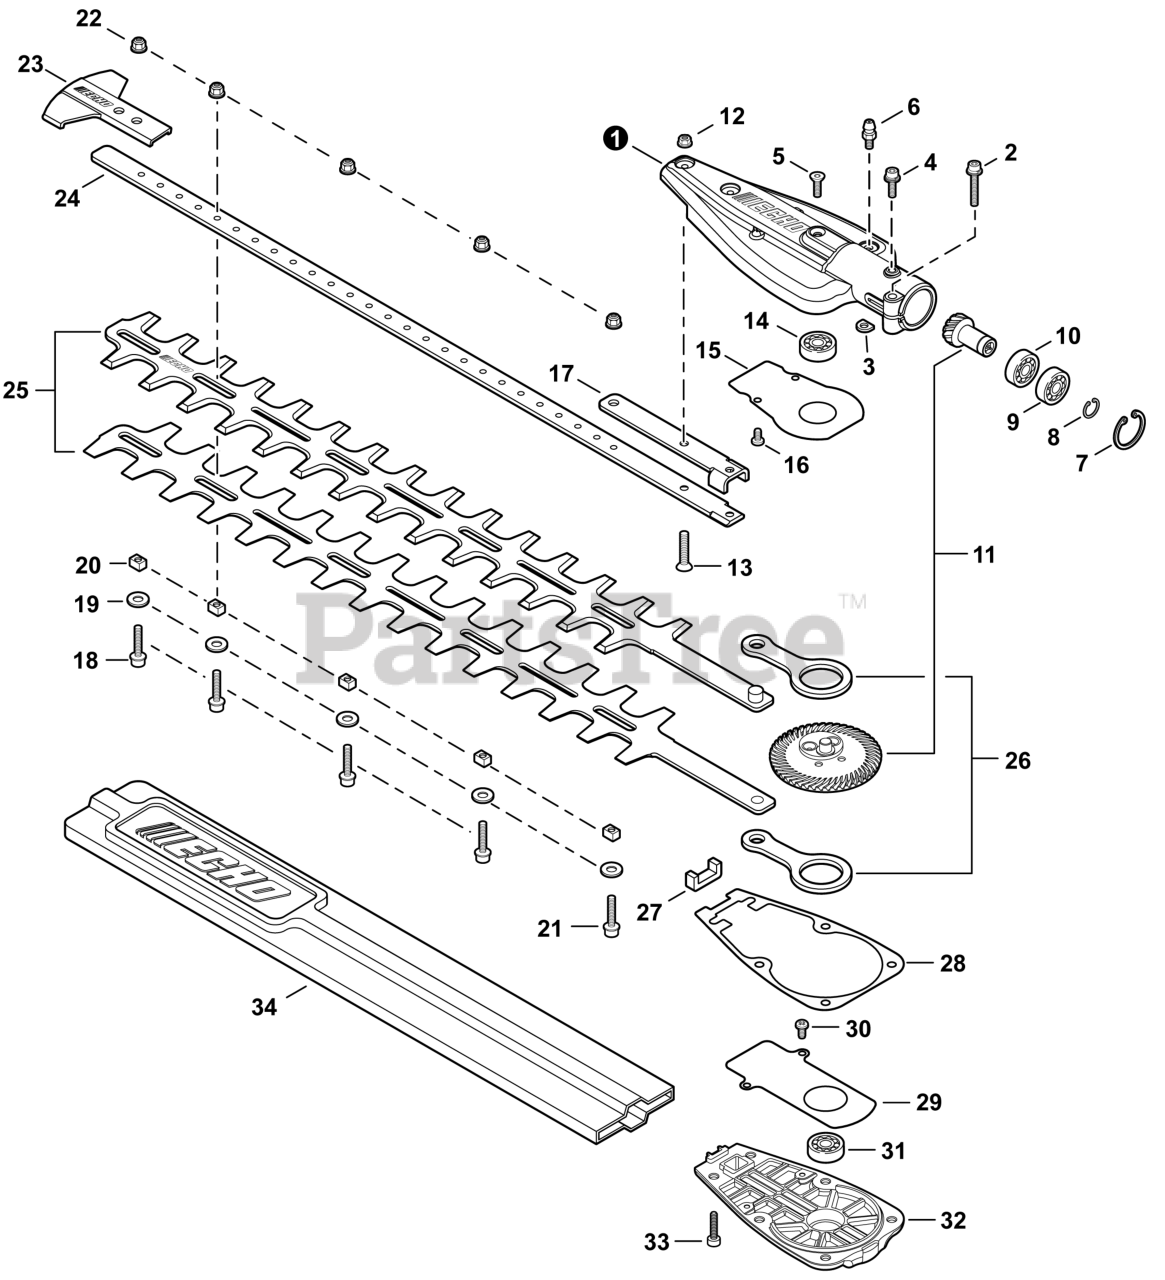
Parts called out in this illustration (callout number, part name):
1	HOUSING, GEAR CASE
2	BOLT 5×25
3	D-WASHER
4	BOLT 5×12
5	SCREW 5×5/8" HD-SOCKET
6	FITTING, GREASE
7	RING, RETAINING Ø24
8	RING, SNAP Ø12
9	BEARING, BALL
10	BEARING, BALL 6901Z
11	GEAR SET
12	NUT, FLANGE M5
13	SCREW 5×18
14	BEARING, BALL 608ZZ
15	PLATE, WEAR
16	SCREW 4×5
17	SUPPORT, BLADE
18	BOLT 5×20
19	WASHER 5
20	GUIDE, BLADE 5
21	BOLT, FLANGE 5×22
22	NUT, FLANGE M5
23	GUARD, TIP
24	SUPPORT, BLADE
25	CUTTER
26	ROD, CONNECTING
28	GASKET, GEAR CASE
29	PLATE, WEAR
30	SCREW 4×5
31	BEARING, BALL 628ZZ
32	COVER, GEAR CASE
33	BOLT 5×12
34	SCABBARD
